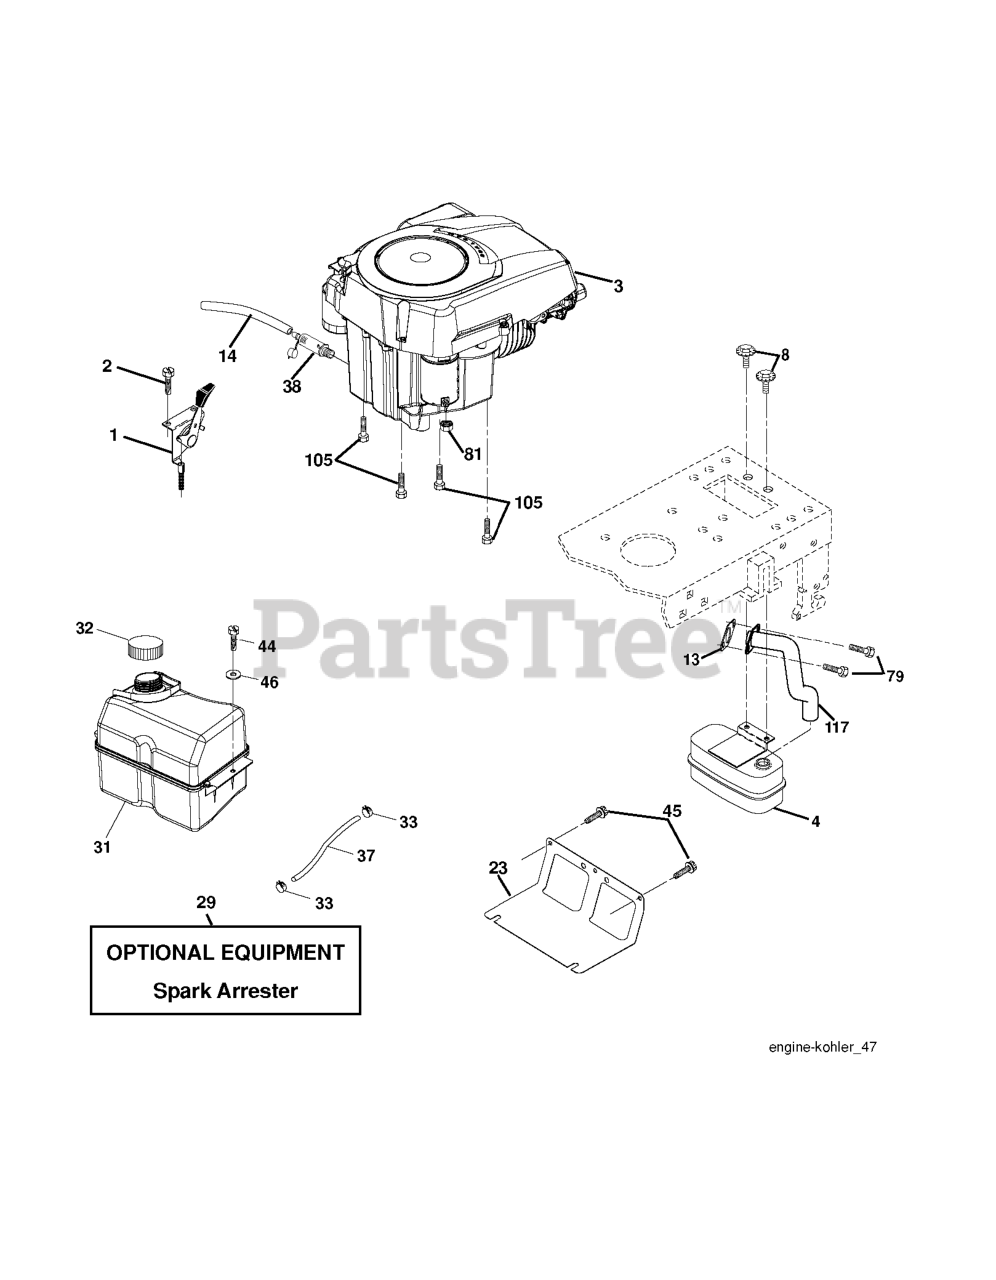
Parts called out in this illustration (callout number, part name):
1	CONTROL.TH/CK.C.
2	SCREW
4	MUFFLER.SINGLE.CYL.KOHL/B&S
8	BOLT.5/16-18UNCX3/4 W/SEMS.BLK
13	GASKET.EXHAUST.KOHLER
14	TUBE, DRAIN OIL ASM.
23	SHIELD.BROWNING.DBR.GUARD
29	KIT.SPARK ARRESTOR 794945 B&S
31	RP TANK FUEL FRT 1.5 GAL
32	FUEL CAP
33	HOSE CLAMP
37	LINE.FUEL.20
38	PLUG DRAIN OIL EASY
44	SCREW HEXWSHR 1/4-20X3/4
45	SCREW, 3/8-16X3/4
79	SCREW.SOCKET HD.5/16-1
81	NUT
105	SCREW 3/8-16X1
117	RP.TUBE.EXHAUST.KOHL.COURAGE
